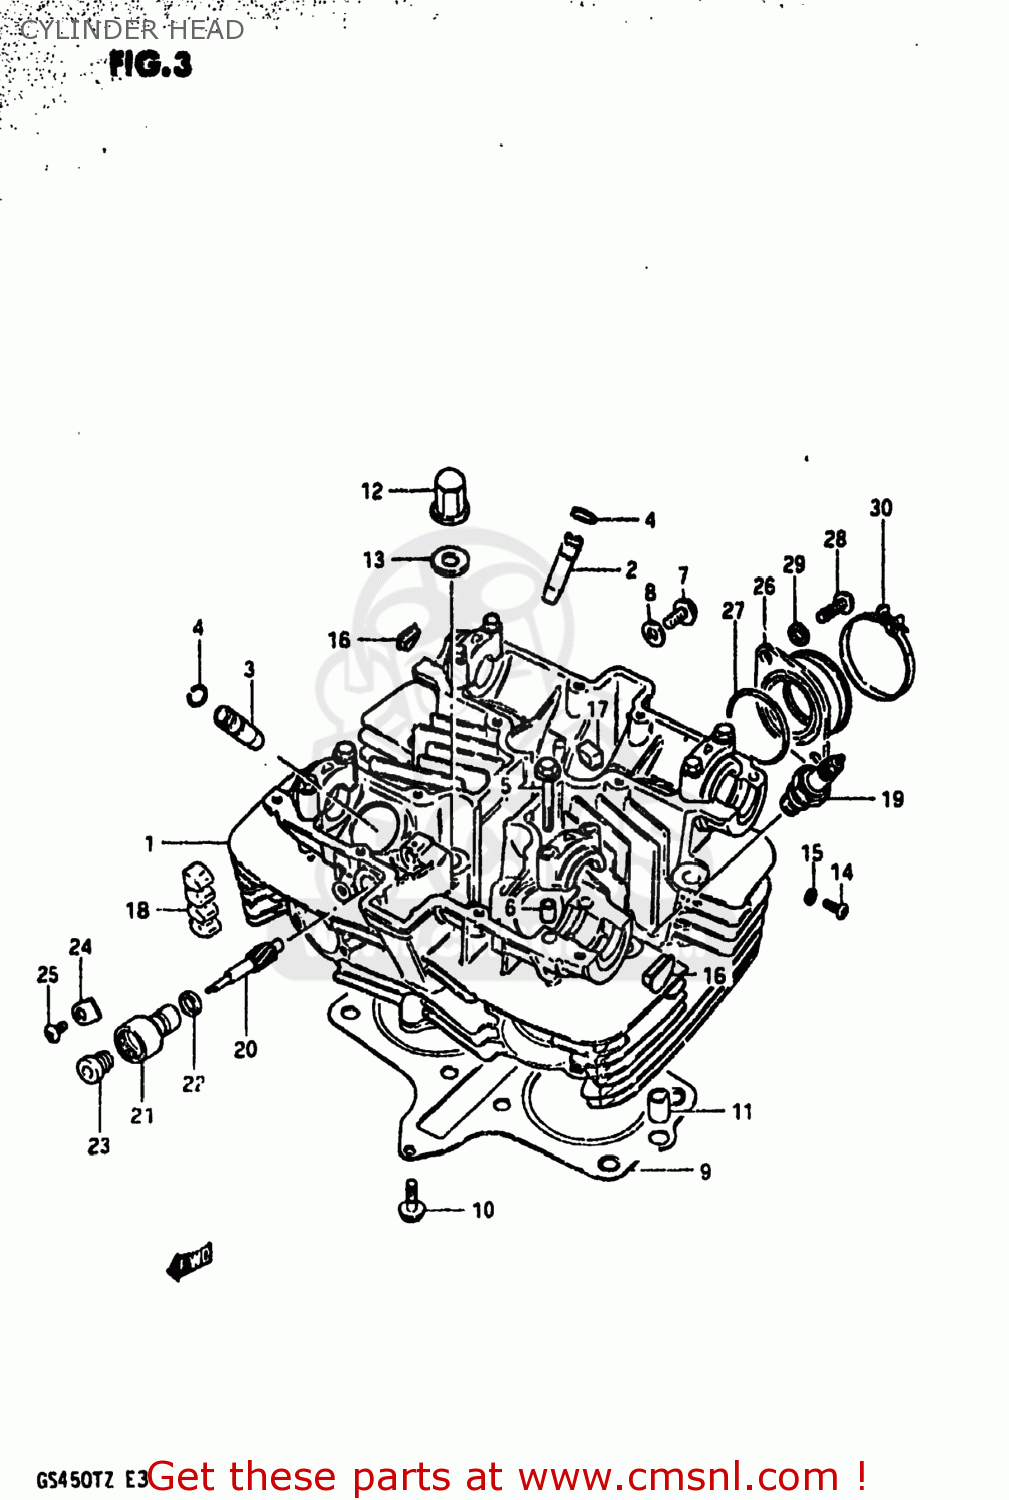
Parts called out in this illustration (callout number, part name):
1	HEAD ASSEMBLY,CYLINDER
2	GUIDE,INTAKE VALVE
3	GUIDE,EXHAUST VALVE
4	RING,SNAP
5	BOLT(6X39)
6	PIN(6.2X8X11)
7	BOLT
8	GASKET (NAS)
9	GASKET,CYLINDER HEAD (MCA)
10	BOLT
11	PIN
12	NUT
13	GASKET (NAS)
14	SCREW
15	GASKET(5.3X9.3X1.2) (NAS)
16	PLUG
17	PAD
18	PAD,CYLINDER
19	SPARK PLUG
20	GEAR,TACHOMETER DRIVEN
21	SLEEVE,TACHOMETER DRIVE
22	SEAL,TACHOMETER DRIVEN
23	SEAL,OIL(5X12X8)
24	PLATE,TACH DRIVE GEAR SLEEVE
25	SCREW(5X12)
26	PIPE,INTAKE
27	O-RING (D:2.4 ID:39.7)
28	SCREW
29	LOCK WASHER
30	CLAMP
